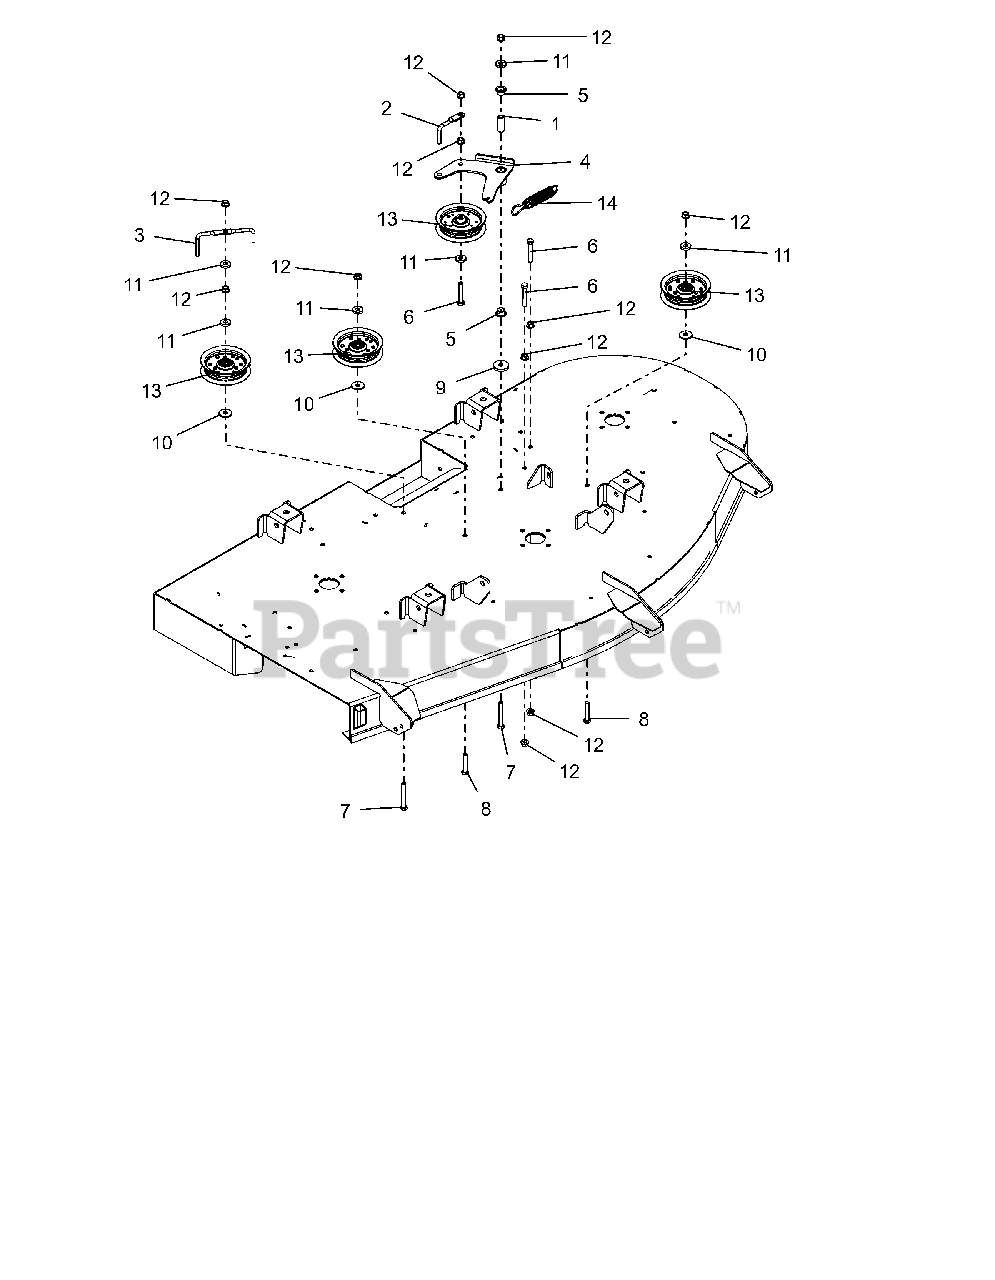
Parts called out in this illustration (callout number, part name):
1	SPACER, .375IDX.625ODX1.66 PM
2	WIREFORM, BELT FINGER
3	WIREFORM, BELT FINGER
4	WLDMT, IDLER ARM-42"
5	BSHG-FLG, .625X.750X.500X1.00
6	@BLT-HEX .38-16X2.25 GR5 YWZC
7	@BLT-HEX .38-16X2.75 GR5 YWZC
8	@BLT-HEX .38-16X2.00 GR5 YWZC
9	WSHR,FLT STL.406X1.50X.245YWZC
10	WSHR FL STL .406X1.25X.10ZC120
11	WSHR-FL-STL .406X1.00X.188 YWZ
12	NUT-LK-TOP-FLG .38-16 ZC120
13	ASM, IDLER 4"
14	SG-TENS .135X.98X6.0 WLD 62
